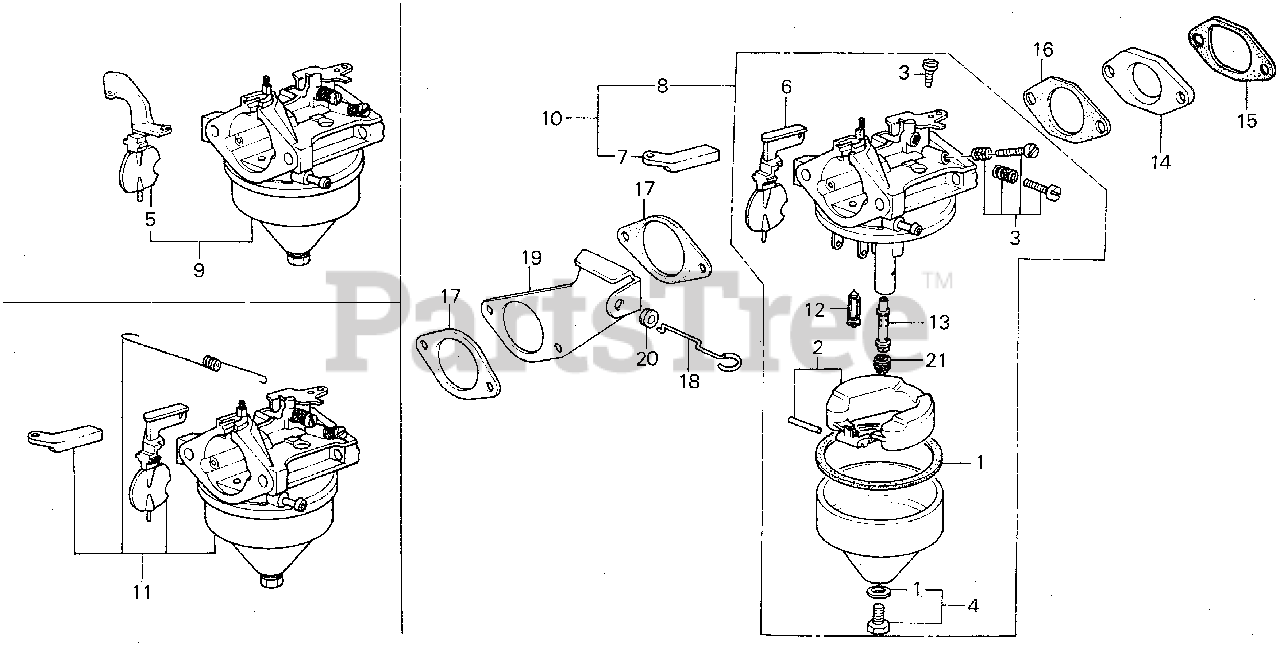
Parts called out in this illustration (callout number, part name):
1	GASKET SET
2	FLOAT SET
3	SCREW SET A
4	SCREW SET
5	CHOKE SET
6	CHOKE SET
7	ARM, CHOKE LEVER
8	CARBURETOR ASSY. (BB30A G)
8	CARBURETOR ASSY. (BB30A D)
9	CARBURETOR ASSY. (BB30A G)
9	CARBURETOR ASSY. (BB30A A)
9	CARBURETOR ASSY. (BB30A D)
10	CARBURETOR ASSY. (BB30A G)
10	CARBURETOR ASSY. (BB30A B)
10	CARBURETOR ASSY. (BB30A D)
11	CARBURETOR ASSY. (BB30A G)
11	CARBURETOR ASSY. (BB30A D)
12	VALVE, FLOAT
13	NOZZLE, MAIN
14	INSULATOR, CARBURETOR
15	GASKET, INSULATOR
16	GASKET, CARBURETOR
17	GASKET, AIR CLEANER
18	ROD, CHOKE CONTROL
19	STAY, CHOKE CONTROL
20	GROMMET, CHOKE ROD
21	JET, MAIN (#65) Use up to Engine SN BB30A D.
21	JET, MAIN (#68) Use up to Engine SN BB30A D.
21	JET, MAIN (#70) Use up to Engine SN BB30A D.
21	JET, MAIN (#72)
